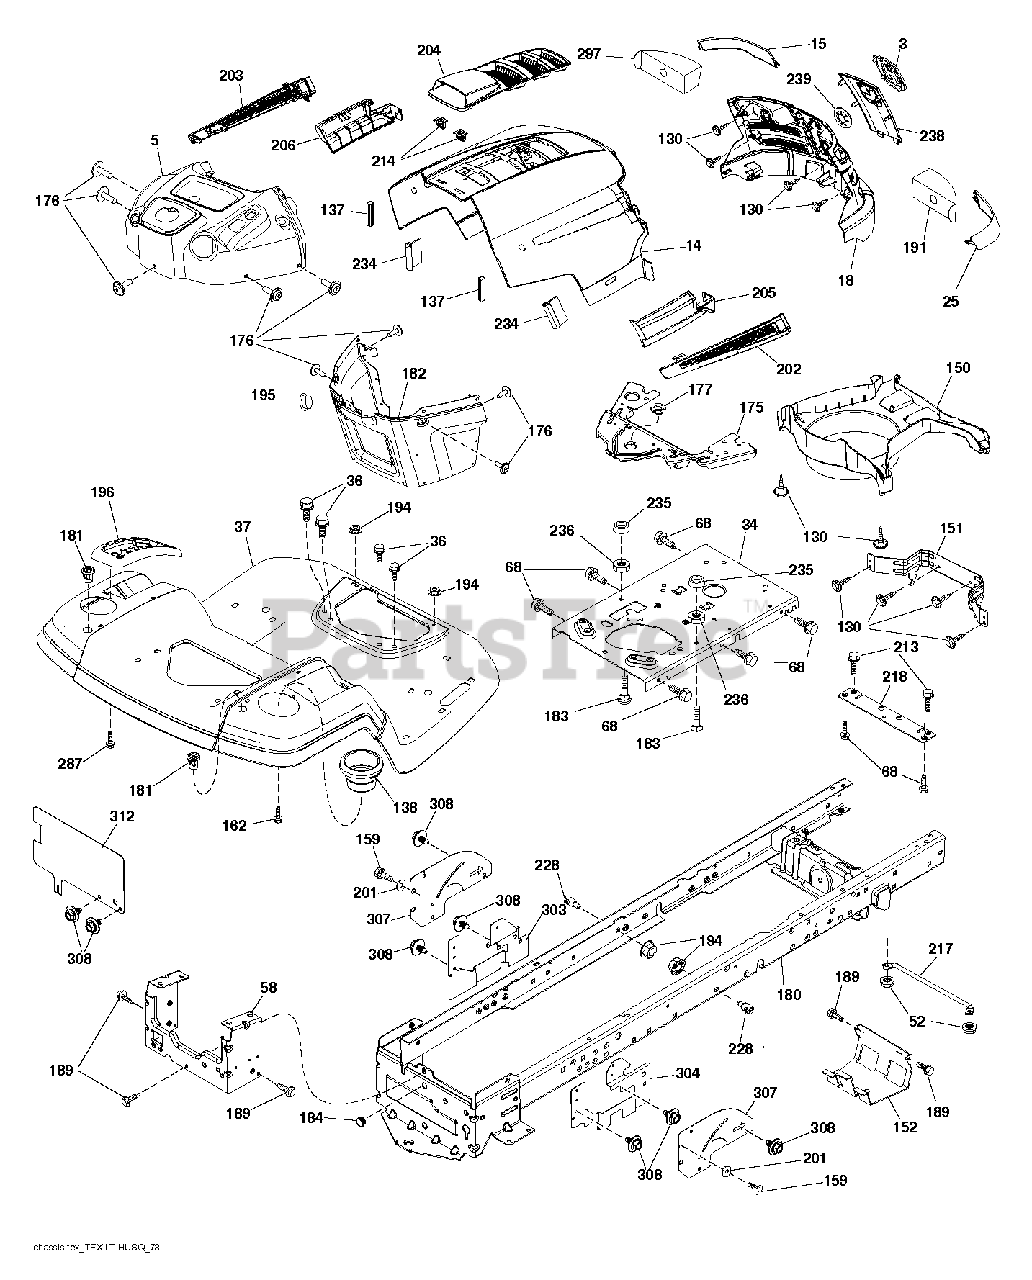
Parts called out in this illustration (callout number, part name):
3	LOGO.HUSQ.GT.LT.CROWN.H
5	DASH.UP.HU.LT.CBL.CLTCH.CHG.PT
14	HOOD.HUSQVARNA.LT.ORANGE
15	LENS.HUSQVARNA LT.RH
18	GRILLE.SVC.HUSQVARNA.GREY
25	LENS.HUSQVARNA LT.RH
34	PLATE.ENGINE.WELDED.CHASSIS
36	SCREW 5/16"
37	FENDER.TLT.PDL.CNTRL.W/CPH.ORG
52	LOCKNUT
58	DRAWBAR UPPER 2PC SMALL FENDER
68	SCREW LT
130	SCREW.#10 X 0.750.BOS
137	BUMPER DASH
138	HOLDER.CUP.LT.GREY
151	BRACKET PIVOT
152	SHIELD.BROWNING.W/TEX
159	SCREW, 3/8-16X3/4
162	SCREW.HI-LO.CONSOLE
175	CROSSMEMBER
176	SCREW.#10-24X5/8.RN.QU
177	BUSHING STEERING
180	CHASS.WLDMNT.TL.12GA/2P.48/54
181	BUSHING.MNT.FEND.CRGO.TEX.49
182	DASH.LOWER.PREDATOR LT
183	BOLT.5/16-18X1-1/4 FULL THD
184	PLUG.DEMO.625
189	SCREW
191	INSERT.REFLECTIVE.RH.
194	NUT LOCK HEX FLANGE 5/16-18
195	PLUG.TEX.DASH.SVC.MINDER.GREY
196	DECKLFT.CONSOL FULL ASSM GREY
201	WASHER
202	VENT.SIDE.HUSQVARNA.LT.RT
203	VENT.SIDE.HUSQVARNA.LT.LFT
204	SUBASM.TOP.VENT.HUSQ.LT
205	SKIRT.SIDE.HUSQVARNA.LT.RT
206	SKIRT.SIDE.HUSQVARNA.LT.LEFT
213	BOLT
214	CLIP.RETAINER.TINNER.
217	ROD.PIVOT.HOOD
218	X-PIECE.HOOD.STOP.NON/
228	STUD.FASTNER.W/ANTI-ROTATE
234	BUMPER.HOOD.TEX.HUSQVARNA
235	SPACER FENDER
236	NUT.CENTERLOCK.5/16-
238	TRIM.HUSQ LT.668
287	SCREW 1/4X20
297	INSERT REFLECTIVE
303	SHIELD.LOWER.LH/LT/GT/BLK.EDIP
304	SHIELD.LWR.RH.LT30DECK.PNT.BLK
304	SHIELD CHASSIS RIGHT
307	SHIELD.UPPER.LT.GT.ISO
308	BOLT, 5/16-18 X 1 3/4
312	Husqvarna TBD
